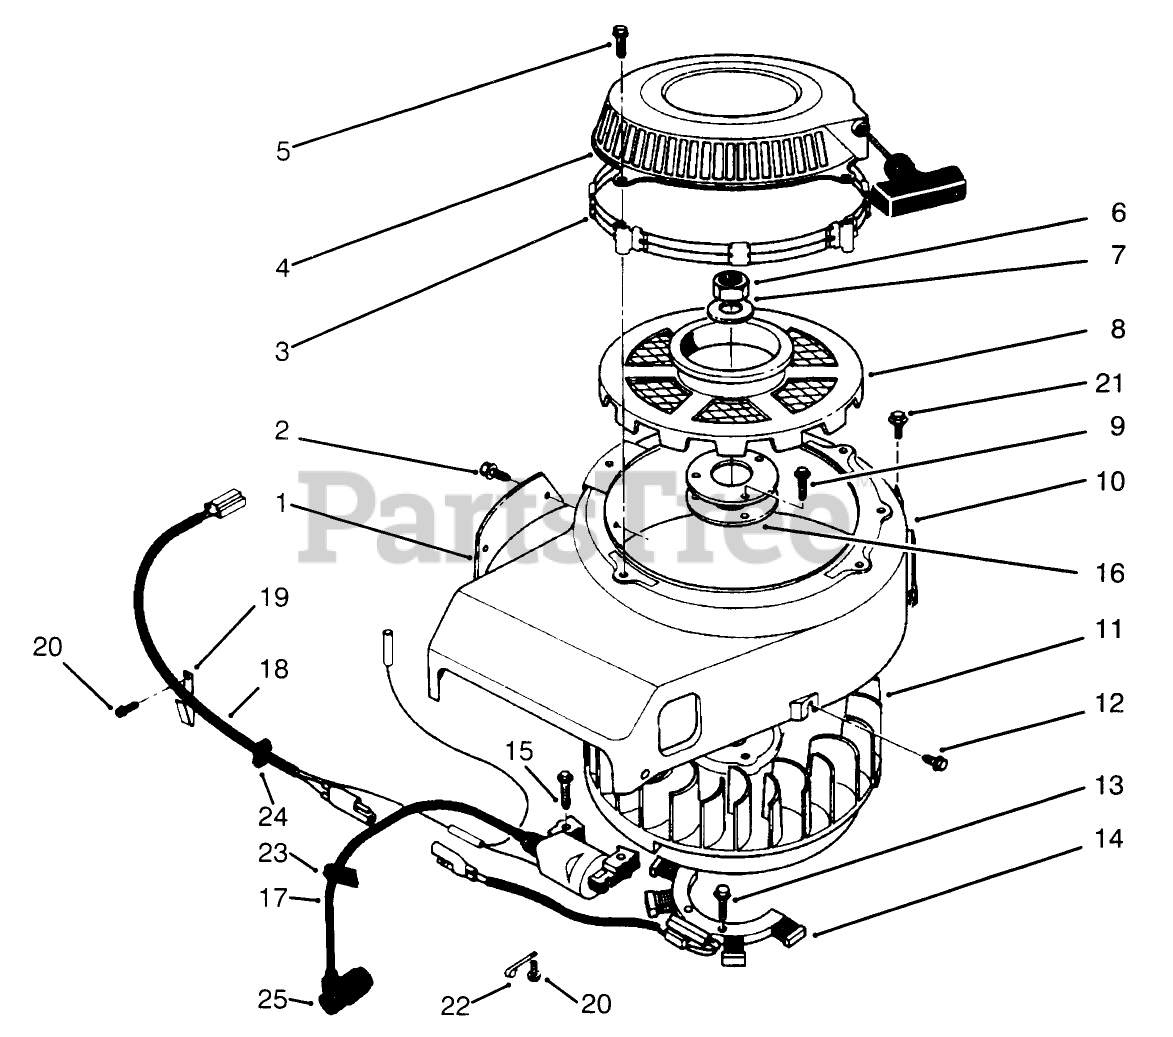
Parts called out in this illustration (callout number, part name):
1	Cover
2	Screw
3	Guard
4	Recoil Starter ASM
5	Bolt-Flanged (6X35)
6	Nut
7	Washer
8	Pulley
9	Bolt-Flanged (8X12)
10	Housing-Fan
11	Flywheel
12	BOLT-FLANGED (6X10)
13	Screw
14	Coil
15	Bolt
16	Shim
17	Coil
18	Harness
19	Clamp
20	Bolt-Flanged (6X10)
21	Bolt-Flanged (6X14)
22	Clamp
23	Grommet
24	Grommet
25	Cap-Spark
